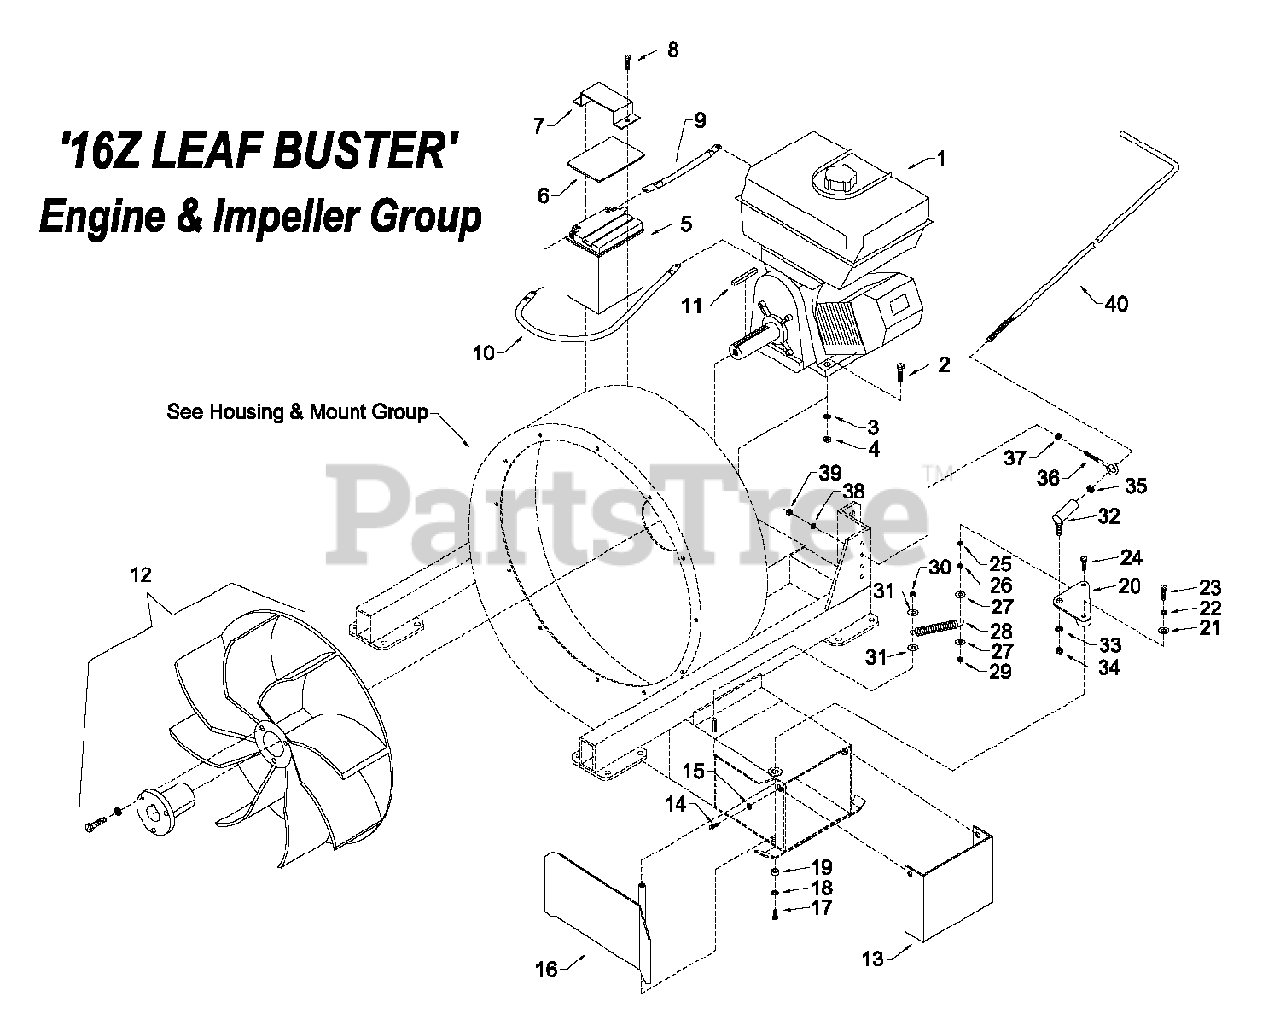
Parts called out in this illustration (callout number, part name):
1	* Engine, 16hp Briggs & Stratton Vanguard
2	Bolt, hex head - 5/16-18 x 1-3/4" gr5
3	Washer, split lock - 5/16"
4	Nut, hex finish - 5/16-18
5	Battery 12N14-3A
6	Pad, rubber battery cover
7	Strap, battery top
8	Bolt, hex head - 5/16-18 x 1" gr5
9	Cable, battery - 8" red - battery positive
10	Cable, battery - 10" black - battery ground
11	Key, engine shaft - 1/4" sq x 2-1/8"
12	Impeller (complete with taper-lok hub)
13	Deflector, side discharge
14	Bolt, hex head - 3/8-16 x 5/8" gr5
15	Washer, split lock - 3/8"
16	Door, forward discharge
17	Bolt, hex head - 5/16-18 x 3/4"
18	Washer, split lock - 5/16"
19	Spacer, 5/16" id x 1/2" od x 1/4"
20	Bell crank, fwd door
21	Washer, flat - 5/16"
22	Washer, split lock - 5/16"
23	Bolt, hex head - 5/16-18 x 1"
24	Bolt, hex head - 5/16-18 x 1"
25	Washer, split lock - 5/16"
26	Nut, hex finish - 5/16-18
27	Washer, flat - 5/16"
28	Spring, forward discharge door
29	Nut, reverse lock - 5/16-18
30	Nut, reverse lock - 3/8-16
31	Washer, flat - 3/8"
32	Linkage, ball joint - 1/2-20
33	Washer, split lock - 1/2"
34	Nut, hex jam - 1/2-20
35	Nut, hex jam - 1/2-20
36	Bolt, turned eye - 5/16-18 x 3-1/4"
37	Nut, hex finish - 5/16-18
38	Washer, split lock - 5/16"
39	Nut, hex finish - 5/16-18
40	Rod, control - fwd discharge door
